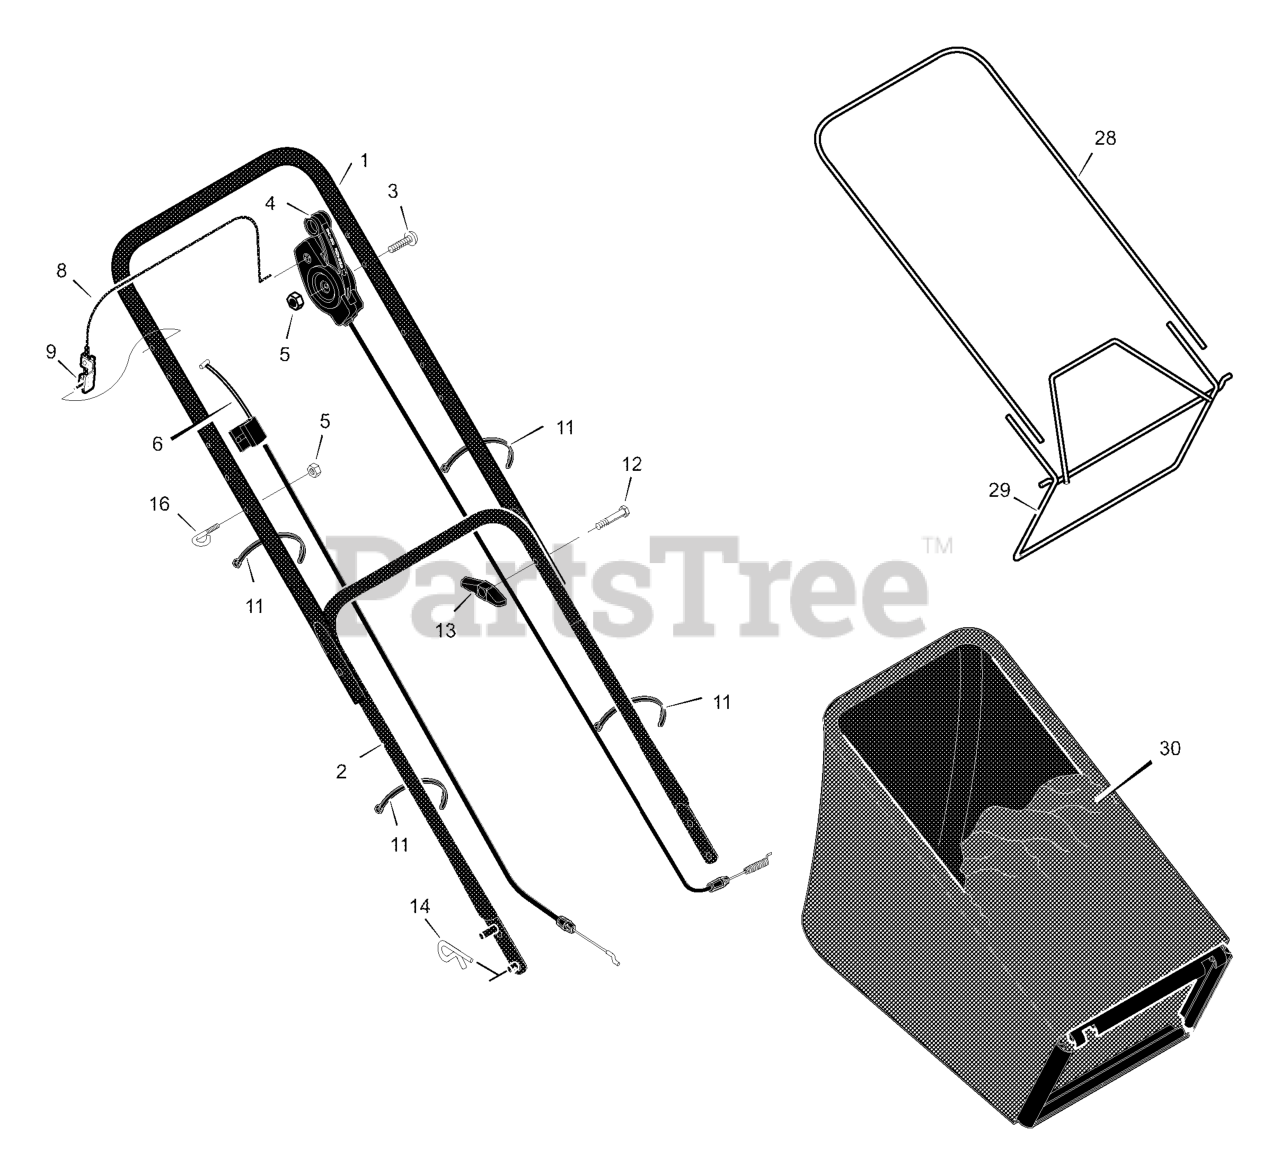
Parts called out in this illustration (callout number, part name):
1	Handle, Upper (Gray)
2	Handle, Lower (Gray)
4	Control, Drive
5	Locknut
6	Cable, Stop
8	Engine Stop Lever
9	Bracket, Stop Lever
11	Fastener, Cable
13	Knob
14	Pin, Hair
16	Guide, Rope
28	Frame, Top
29	Frame Assembly
30	Bag, Cloth
